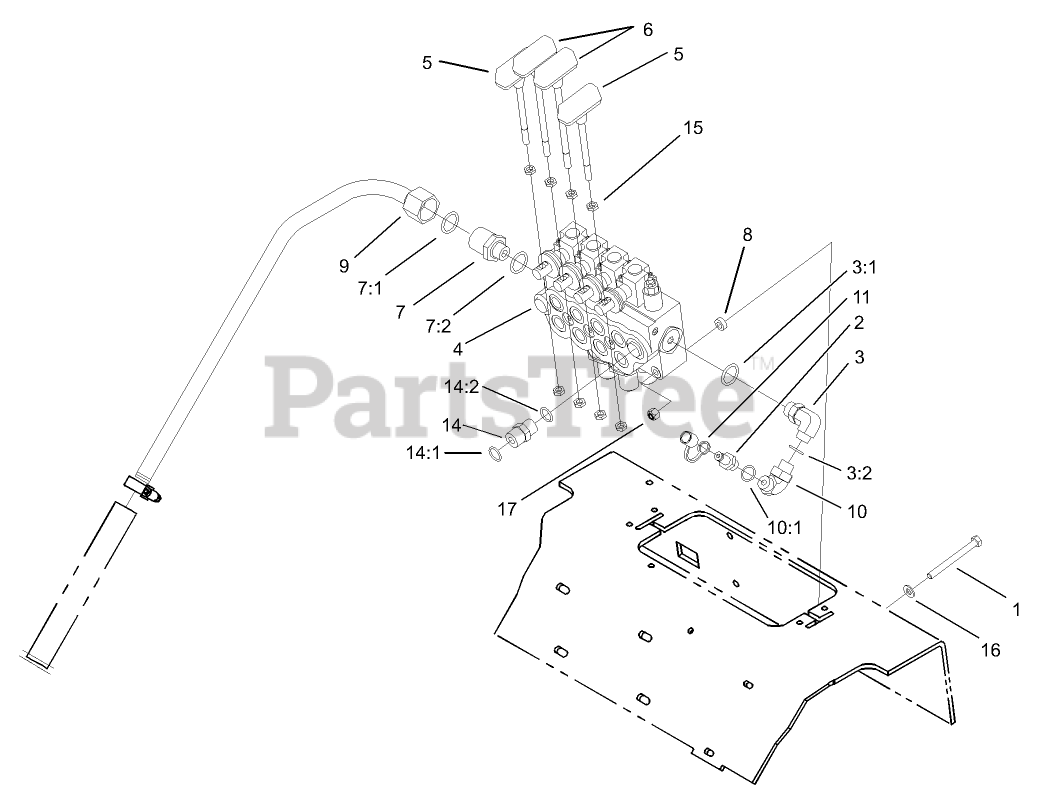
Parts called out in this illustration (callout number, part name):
1	SCREW-HH
2	NIPPLE-TEST
3	FITTING-HYD, 90 DEG
3:1	O-RING
3:2	O-RING
4	VALVE-HYD, 4-SPOOL
5	CYLINDER HANDLE ASM
6	DRIVE HANDLE ASM
7	FITTING-STR
7:1	O-RING
7:2	O-RING
8	SPACER
9	HYD TUBE ASM
10	FITTING-HYD, 90 DEG
10:1	O-RING
11	CAP-DUST
14	FITTING-STRAIGHT
14:1	O-RING
14:2	O-RING
15	NUT-HEX
16	WASHER-PLAIN
17	NUT-LOCK, NI
